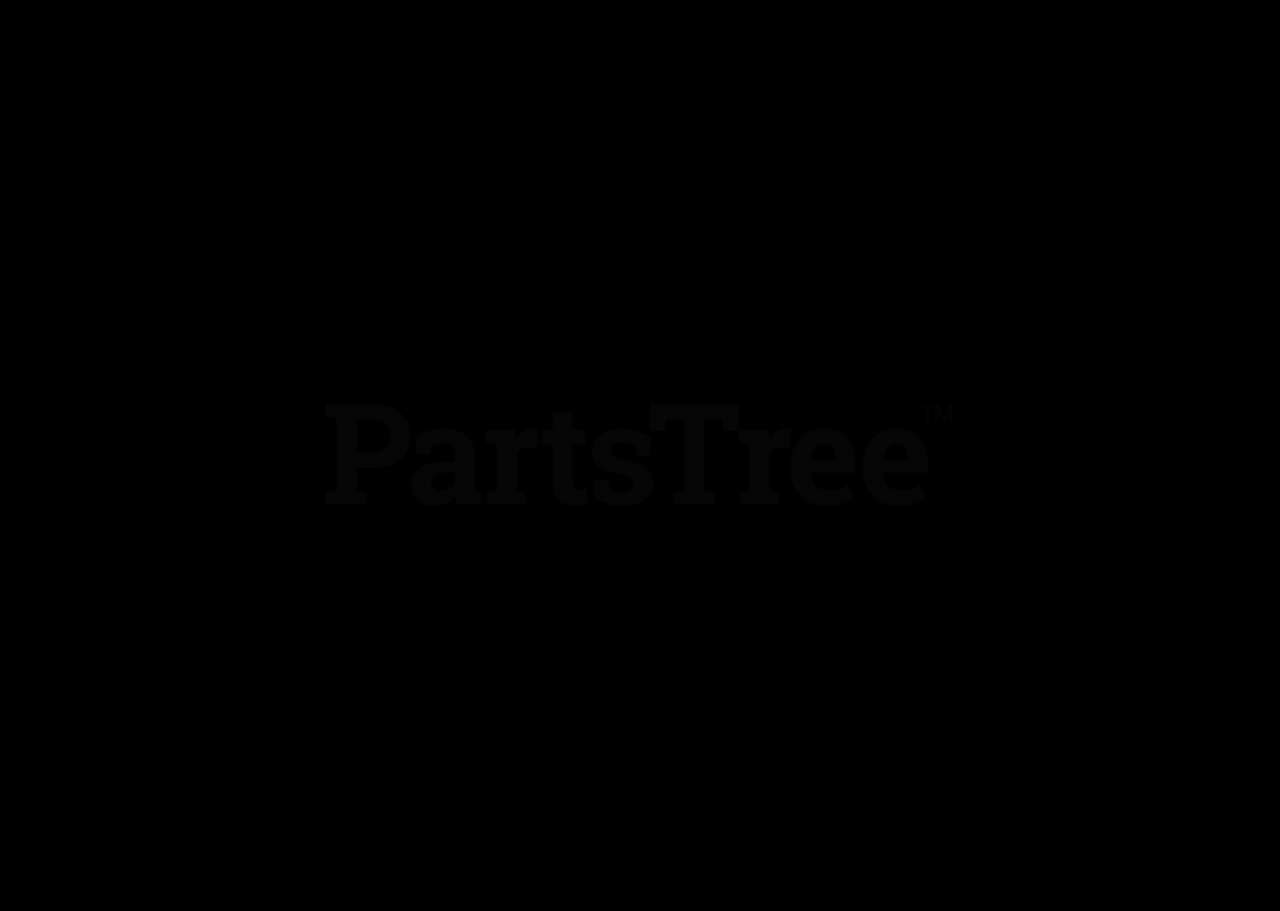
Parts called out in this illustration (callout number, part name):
1	Fork, Front
2	Bearing, Cone
3	Bearing, Cup 2.328 x .465
4	Bearing Seal 1.75 x 2.332 x .312
5	Spacer, 1.258ID x 1.750OD x .550
6	Spacer, Wheel
7	Wheel/Tire Assembly, 15 x 6-6 Smooth
8	Bolt, Hex .50-13 x 9.00 Grade 5
9	Nut-Locking-Top-Flange .50-13
10	Tire/Wheel Assembly, 24 x 11.50-12
11	Bolt, Lug .50-20 x 1.38
12	Wheel Motor, 18E (CCW)
13	Bolt, Wheel Motor .50-13 x 2.75 Grade 8
14	Washer, Flat Steel, .812 x 1.50 x .135
15	Nut, Jam Center-Lock .75-16
16	Cap, Dust
17	Bearing, 25mm I.D. x 52mm OD x 15mm
18	Bolt, Hex .31-18 x 1.50 Grade 8 EP30
19	Waher, Lock .31 x .078
20	Kit, Parking Brake Service
21	Nut, Locking-Jam-Patch 1.00-20
22	Wheel Motor Seal Kit #21544012
